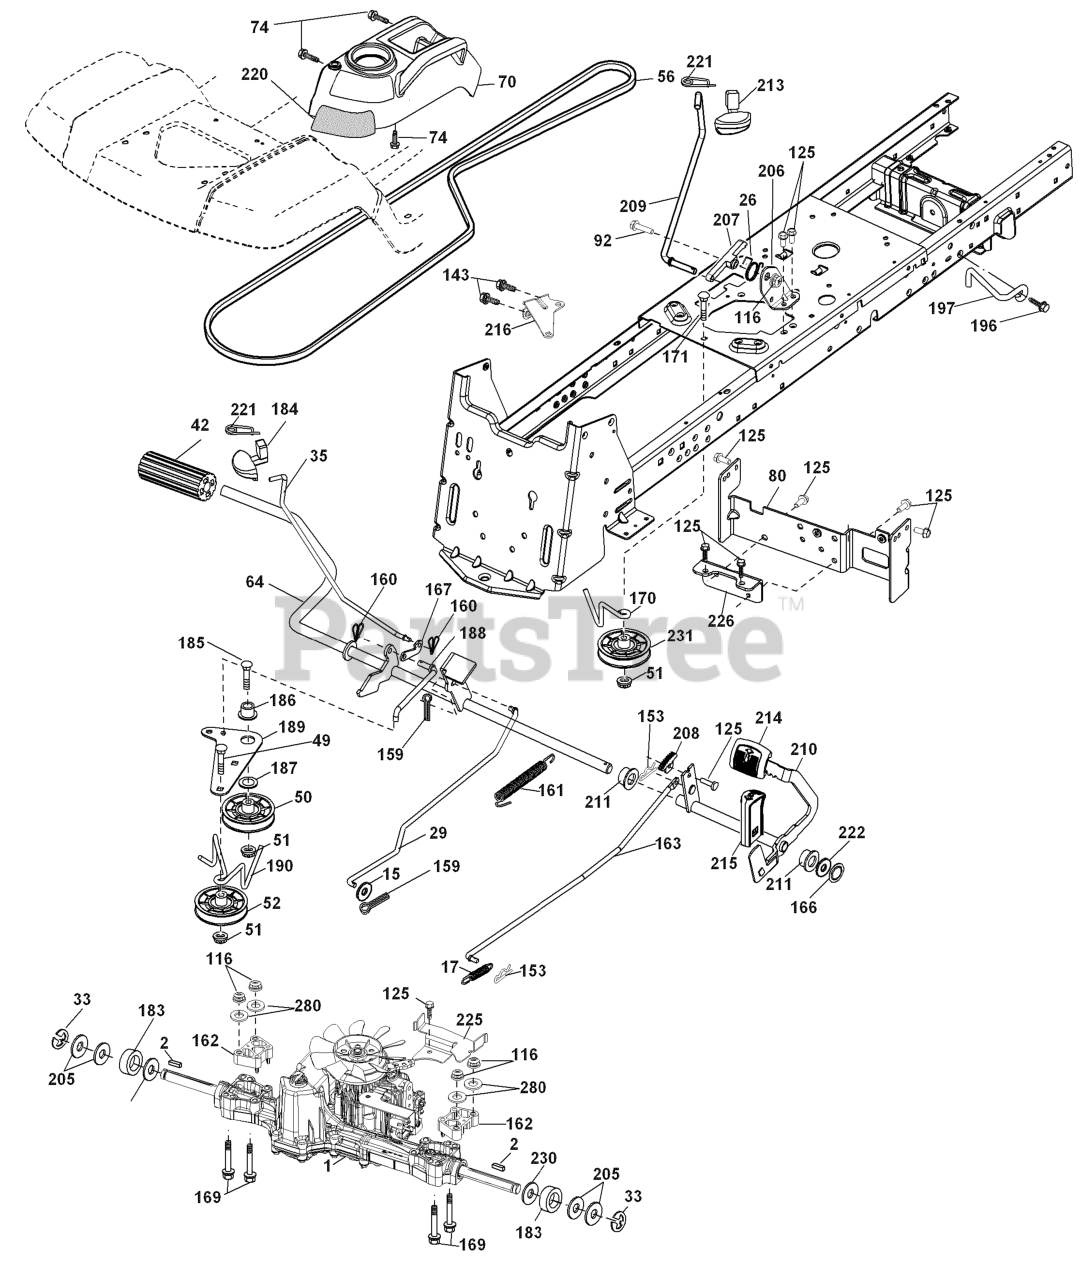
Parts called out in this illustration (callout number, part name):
1	TRANSAXLE.K46BN.PEDAL CONTROL
2	SQUARE KEY
7	HUB.ASM.WHEEL.REAR.22"
9	HUB BOLT
15	WASHER
17	SPRING.BRAKE.K46
26	SPRING.RETURN.CRUISE
29	ROD.BRAKE.K46
35	ROD.BRAKE.PARKING.GT.H
42	PEDAL COVER T
50	IDLER.FLAT.910.OFFSET
51	NUT LOCK FLG 3/8-16 UNC
52	IDLER.V-GROOVE.910.OFFSET
56	V-BELT.MOWER.92.40.42/K46
64	SHAFT.ASM.PEDAL.BRK.CNTR
70	RP CONSOLE.ASM.PCH.W/TB
74	SCREW.HI-LO.CONSOLE
80	STRAP TORQUE
92	BOLT
116	NUT LOCK HEX FLANGE 5/16-18
125	SCREW
143	Screw Thdrol 5/16-18 x 1/2
153	RETAINER M
159	COTTER PIN
160	RETAINER CLIP
161	SPRING.RETURN.CLUTCH.2006
162	SPACER TRANS
163	ROD.CONTROL.PEDAL.K46
166	NUT.PUSH.625.2006
167	LATCH.BRAKE.SPRING
169	BOLT YT
170	KEEPER.V-IDLER.CENTER.
183	SPACER AXLE
184	HANDLE.PARKG.BRK.HUSQ X667
185	BOLT
186	SPACER.RETAINER
187	WASHER 12/32X2X10GA
188	RP.LINK.CLUTCH.GROUND.DRIVE
189	BELLCRANK.GROUND.DRIVE.TEX.
190	KEEPER.BELLCRANK.DRIVE
196	SCREW 3/8-16X1
197	BRKT.ANIT-ROTATION.CLUTCH
206	BRKT.MOUNT.LATCH.CRUIS
207	LATCH.CONTROL.CRUISE
208	GEAR.SECTOR.CONTROL.CR
209	ROD.CONTROL.CRUISE.GT.
210	ROCKER.ASM.PEDAL.CONTR
211	BEARING.NYLON
213	KNOB.CONTROL.CRUSIE.HU
214	PEDAL.FORWARD.TEX.GT.4
215	PEDAL.REVERSE.TEX.GT.4
216	BRACKET.PULLEY.IDLER.W/TEX
220	REFLECTOR.RH.TEX GT
221	RETAINER.SPRING.CLIP.H
222	WASHER
225	KEEPER.BELT.TRANSAXLE.K46
226	BRACKET.MOUNT.TORQUE.K46.TLT
230	WASHER.HARDENED
231	IDLER.V-GROOVE.1.688.OFFSET
280	WASHER T
